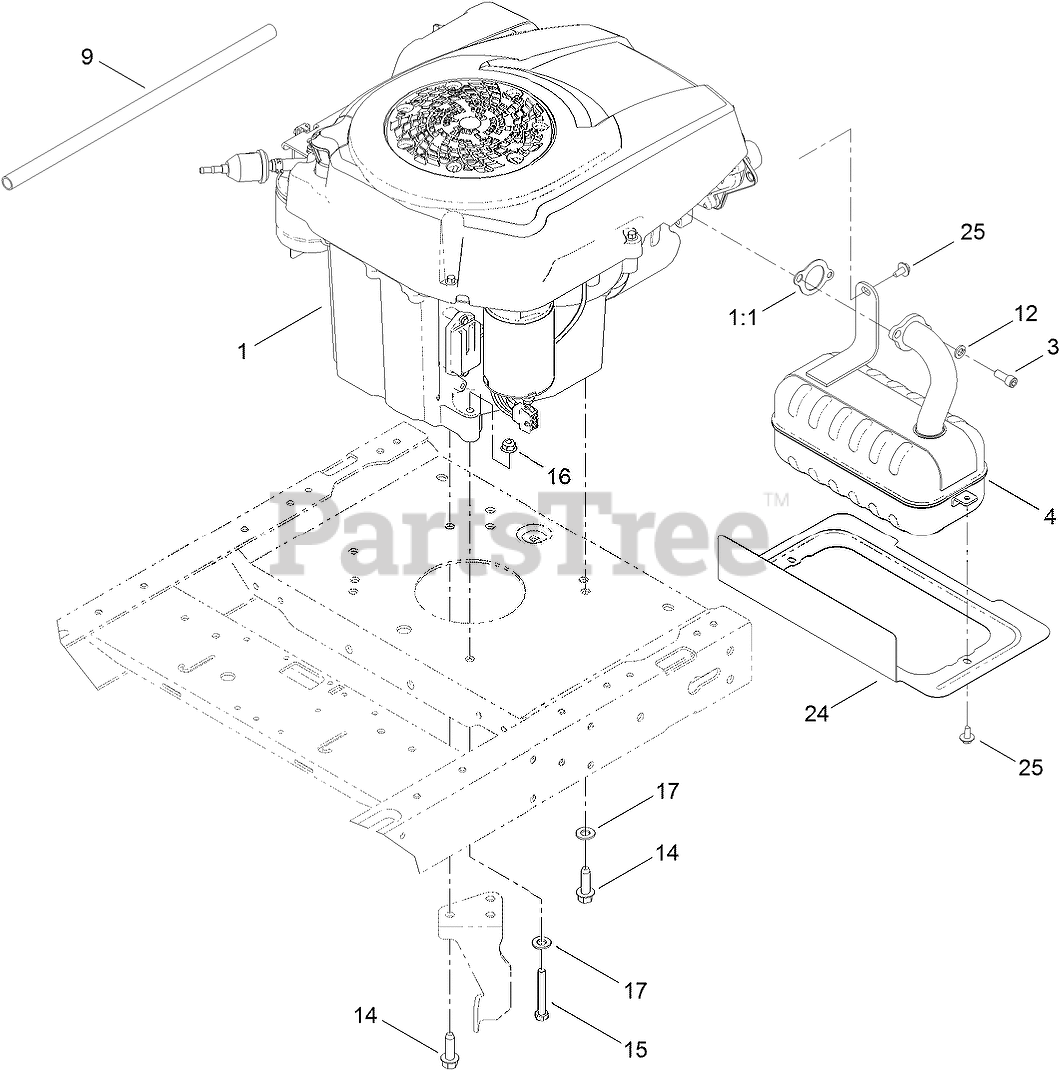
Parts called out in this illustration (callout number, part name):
1:1	GASKET-EXHAUST
3	SCREW-HSH
4	MUFFLER-KOHLER
9	TUBE-DRAIN, OIL
12	WASHER-LOCK
14	SCREW-TAPTITE
15	SCREW-HH
16	NUT-HF, NI
17	WASHER-FLAT
24	SHIELD-HEAT
25	SCREW-HHFTF
